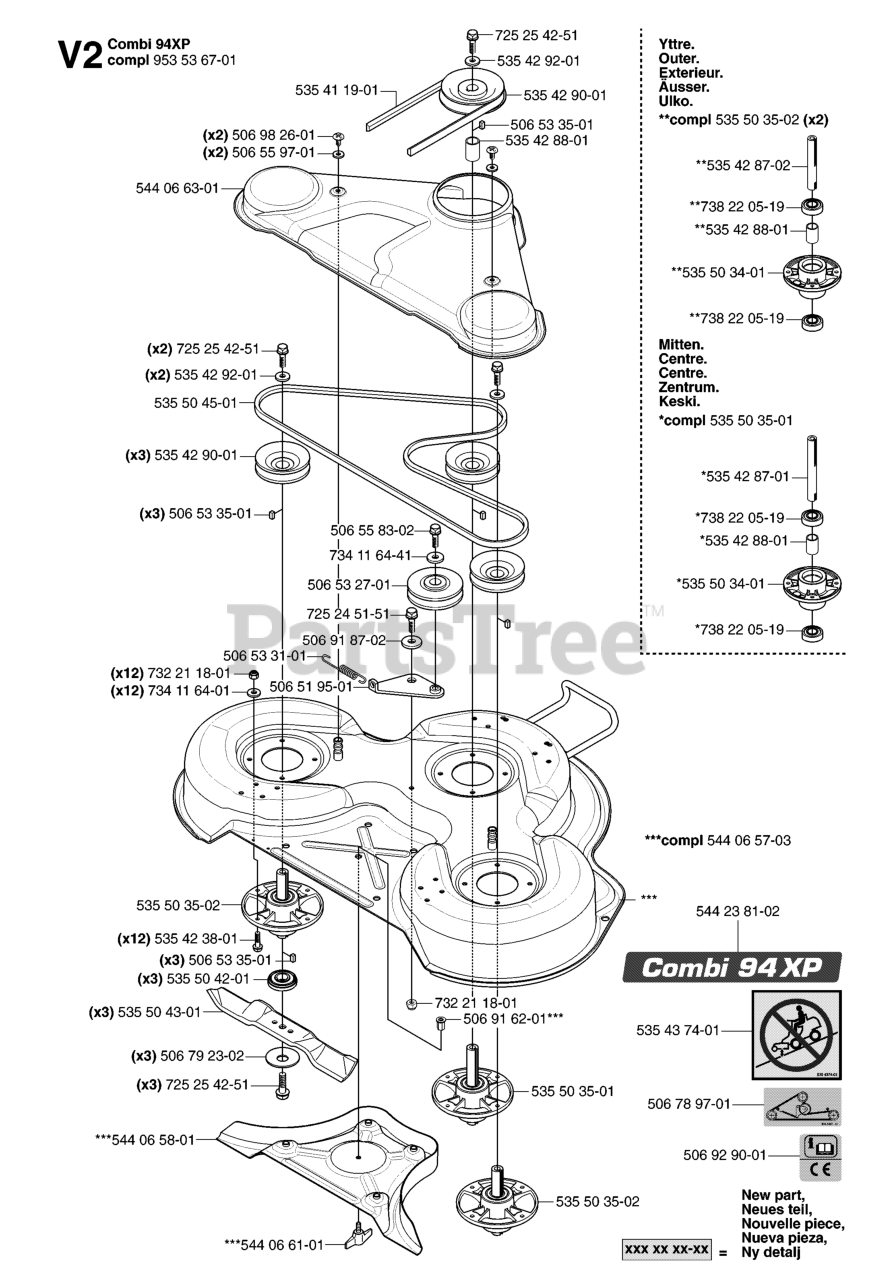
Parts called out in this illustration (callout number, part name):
1	TRANSAXLE ASSEMBLY
2	SPRING BRAKE
3	PULLEY, TRANSAXLE
8	ROD SHIFT FENDER
9	CLUTCH.ELECT.EVX.
10	PIN COTTER
16	NUT.71038.31-18.HEX.NYLOCK
19	NUT
20	BOLT HEX
21	KNOB.DELUXE.(PISTOL.GRIP).BLAC
22	ROD BRAKE HYDRO
23	BRACKET, ASM CLUTCH MTG
24	NUT
25	SPRING ROD LT
26	WASHER
27	COTTER PIN
28	ROD BRAKE PARK LT
29	PLUNGER CAP
30	BRACKET TRANSAXLE
32	BOLT
33	RP BOLT 5/16-18 X3/4 ZN/YEL GR
34	SHAFT, FOOT PEDAL
35	BEARING.NYLON
37	DRIVE PIN
38	FLAT IDLER PULLEY
41	KEEPER.BELT.IDLER.FLAT
42	WASHER
47	IDLER PULLEY
48	BELLCRANK, CLUTCH
49	RETAIN BELT
50	BOLT
52	LOCKNUT
53	LINK, CLUTCH LT
55	SPRING, RETURN LT
57	DRIVE BELT, LTH & YTH TRACTORS
59	KEEPER CENTER SPAN
61	SCREW
62	COVER, PEDAL (1 2)
63	PULLEY, CLUTCH ELECT EVX
65	LOCKWASHER
66	KEEPER BELT ENGINE
71	STRAP LH TORQUE
73	STRAP TORQUE RH HYDRO
74	SPACER SPLIT
77	SQUARE KEY
81	SHAFT ASSY
82	SPRING,TORSION
83	WASHER
89	SHIFT CONSOLE
90	NUT.PUSH.3/16
93	LINE FUEL HYD 4"
94	FAN 7" HYDRO
95	CONTROL ARM, BYPASS HYDRO
96	RETAINER M
97	KEEPER BELT RH
100	WASHER M
103	NUT.HEX.1/2-20
104	CONTROL ARM
106	BOLT.5/16-18X1-1/4 FULL.THREAD
144	Washer 11/32 x 5/8 x 16 Ga SD
146	Bolt Hex Flanged 5/16-18 Unc x 2
147	Bolt Hex Flanged 5/16-18 Unc x 2
149	SPACER RETAINER
150	BUSHING NYLON COLLERED
151	WASHER 12/32X2X10GA
